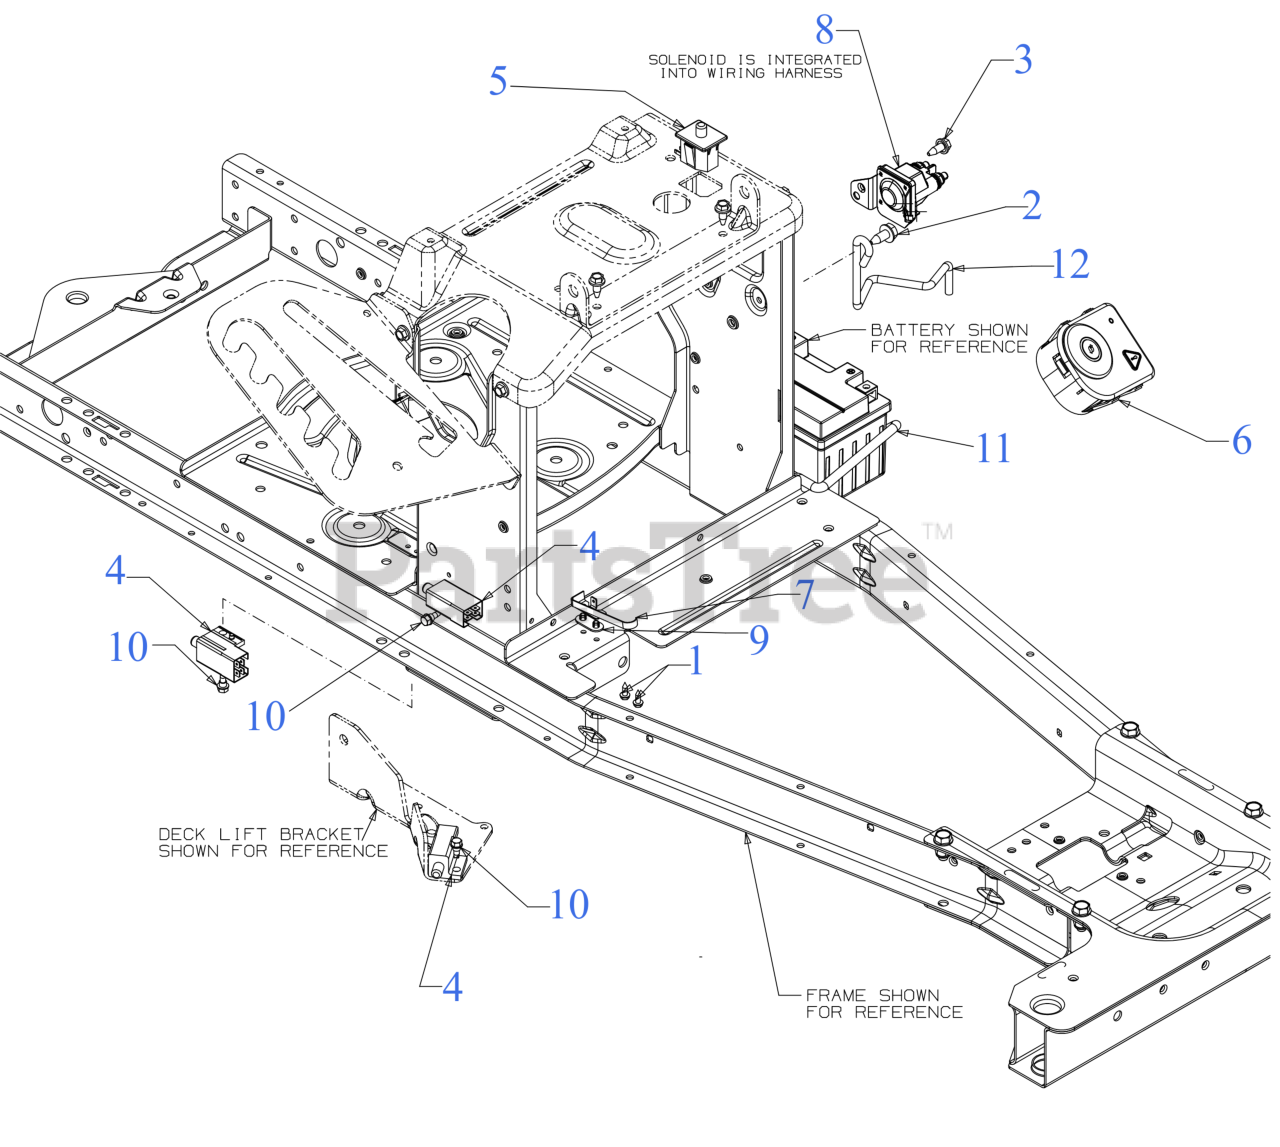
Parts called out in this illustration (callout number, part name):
1	HEX SCREW WASHER HD #8-18 x 0.500
2	SCREW 5/16-18 x .750
3	SCREW 1/4-20X.625
4	INTERLOCK SWITCH (NO/NC)
5	SEAT SWITCH N/C,N/C
6	IGNITION MODULE SWITCH RMC (MAN PTO BLK)
7	SPRING SWITCH
8	HARNESS (RMC SOL AC/DC AGM)
8	12V SOLENOID
9	INSULATOR NUT PLATE
10	SHOULDER SCREW
11	BATTERY TRAY ROD
12	BATTERY HOLD DOWN ROD
